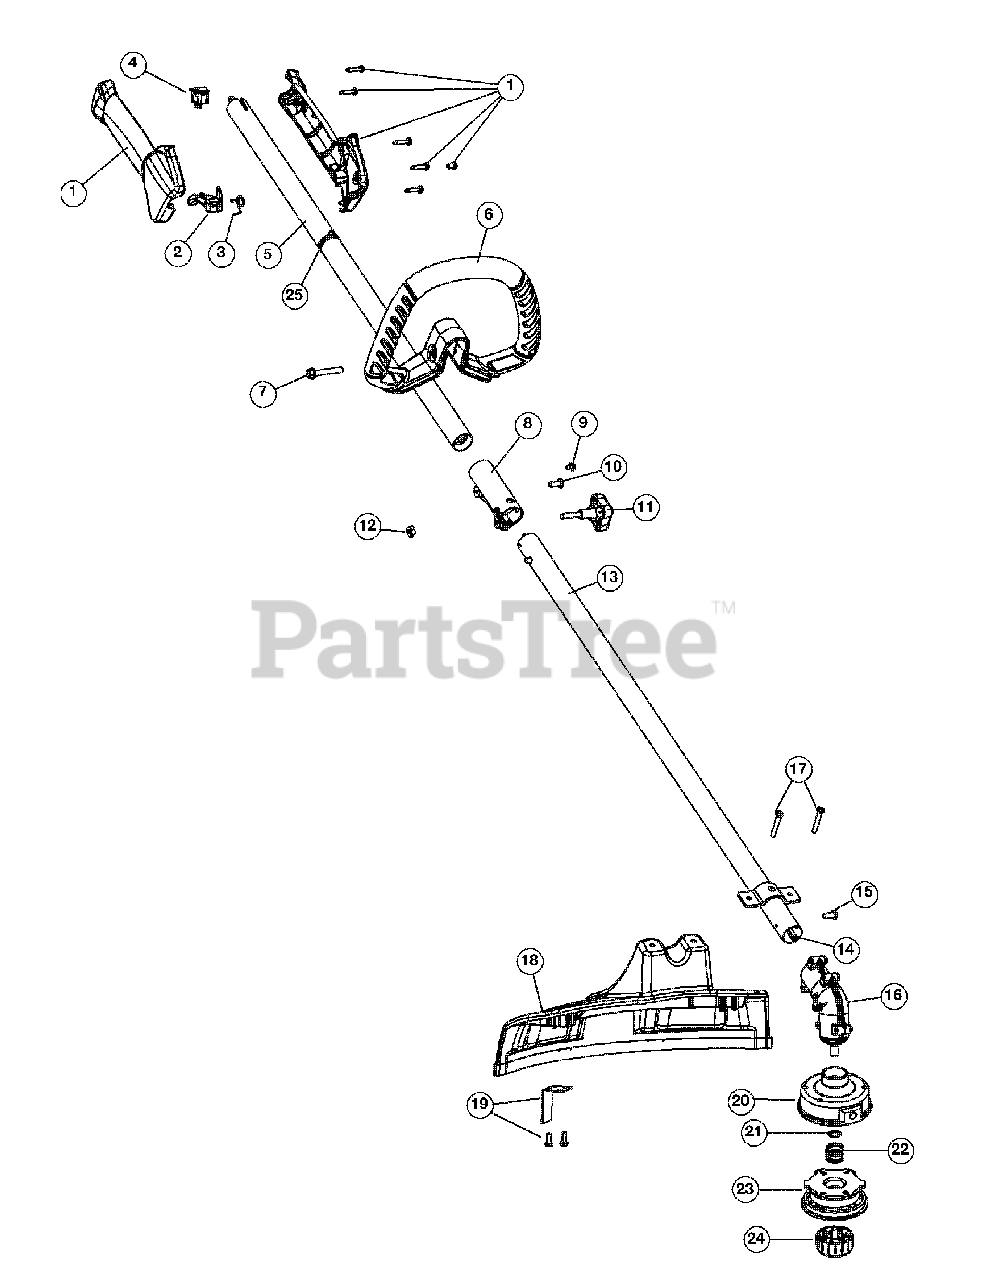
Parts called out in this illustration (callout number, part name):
1	Throttle Housing Assembly
2	Throttle Trigger
3	Throttle Trigger Spring
5	Upper Srive Shaft Housing Assembly
6	Deluxe D-Handle Assembly
8	Split Boom Coupler
11	Adjustment Knob
12	Knob Retaining Nut
13	Lower Drive Shaft Housing Assembly
14	Lower Flexible Drive Shaft
15	Anit-Rotation Screw
16	Gearbox Assembly
17	Shield Mounting Screws
18	Shield Assembly
19	Blade Assembly
20	Outer Spool Assembly
23	Inner Reel
24	Bump Knob Assembly
25	Shoulder Strap Clip
